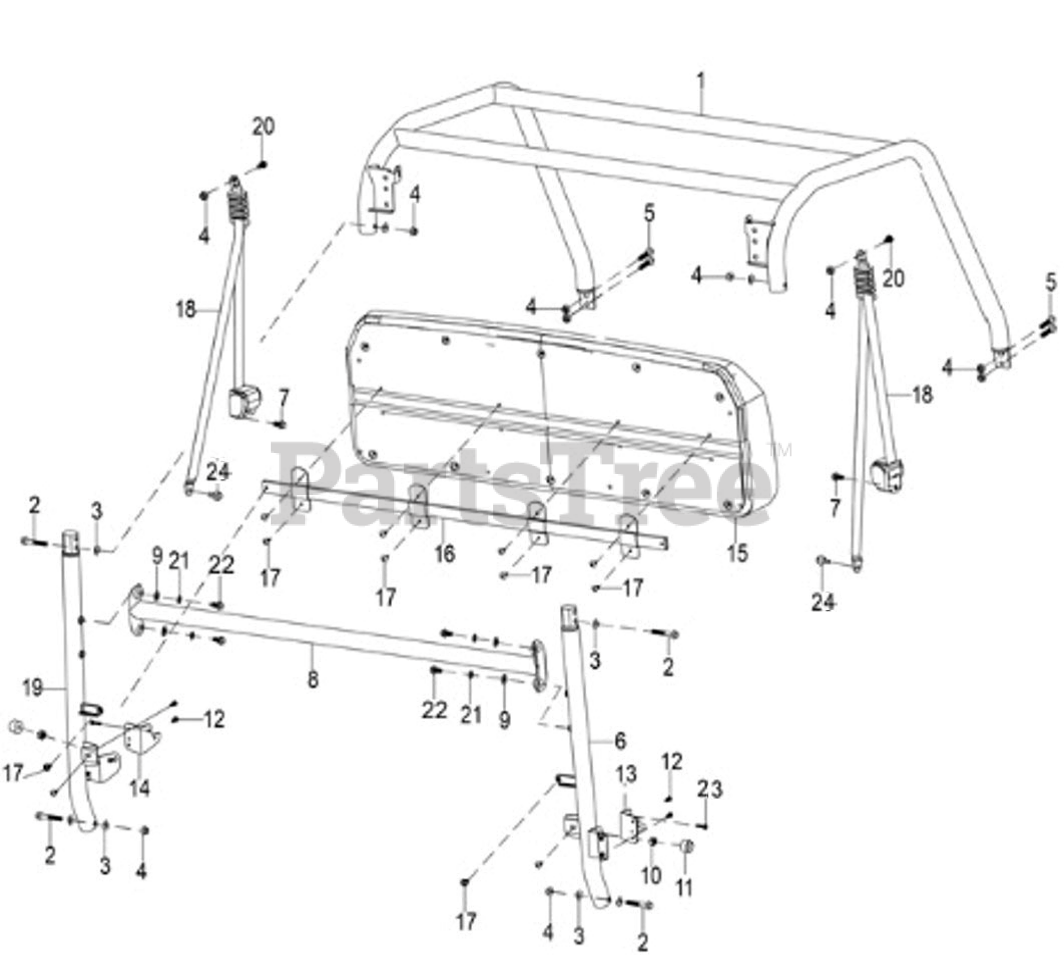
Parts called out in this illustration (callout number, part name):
1	FRONT ROPS
2	HEX NUT M10X1.25X65
3	CURVED WASHER
4	LOCK NUT M10X1.25
5	HEX FLANGE BOLT M10X1.25X50
6	ROPS TUBE (REAR) (RH)
7	HEX FLANGE BOLT (M10x20)
8	ROPS TUBE (REAR) (CROSS)
10	HEX FLANG NUT M6
11	DOOR SPACER
12	SOCKET HEX FLAT HEAD BOLT M6X16
13	DOOR STRIKER (RH)
14	DOOR STRIKER (LH)
15	BENCH SEAT (BACKREST)
16	BRACKET - BACKREST KIT
17	SCREW M6X16
18	SEAT BELT BUCKLE ASSEMBLY
19	ROPS TUBE (REAR) (LH)
20	SHOULDER FLANGE BOLT M10X14X9X25
21	SPRING WASHER
22	HEX FLANGE BOLT M10X1.25X20
23	HEX HEAD FLANGE BOLT M6X12
24	SHOULDER SCREW M10-1.25
